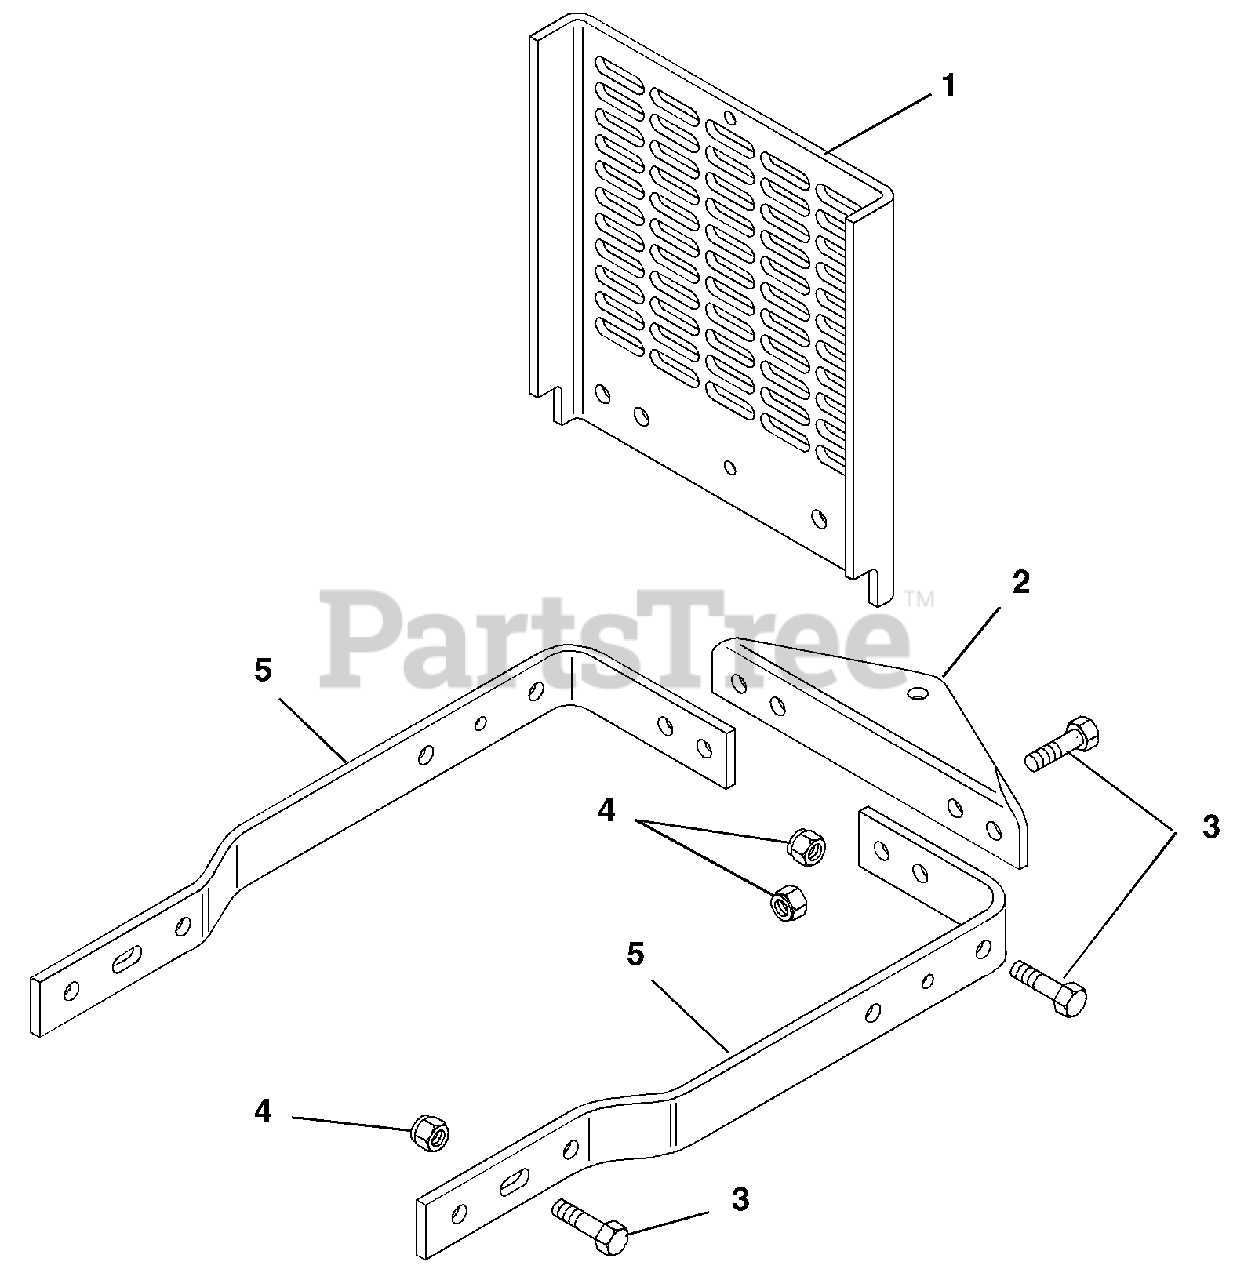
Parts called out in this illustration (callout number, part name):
1	Weldment, Engine Guard
1	Guard, Engine
2	Plate, Hitch
3	Bolt-Hex .50-13 x 1.75 Grade 8
4	Nut-Locking-Center .50-13
5	Arm, Rear Hitch
